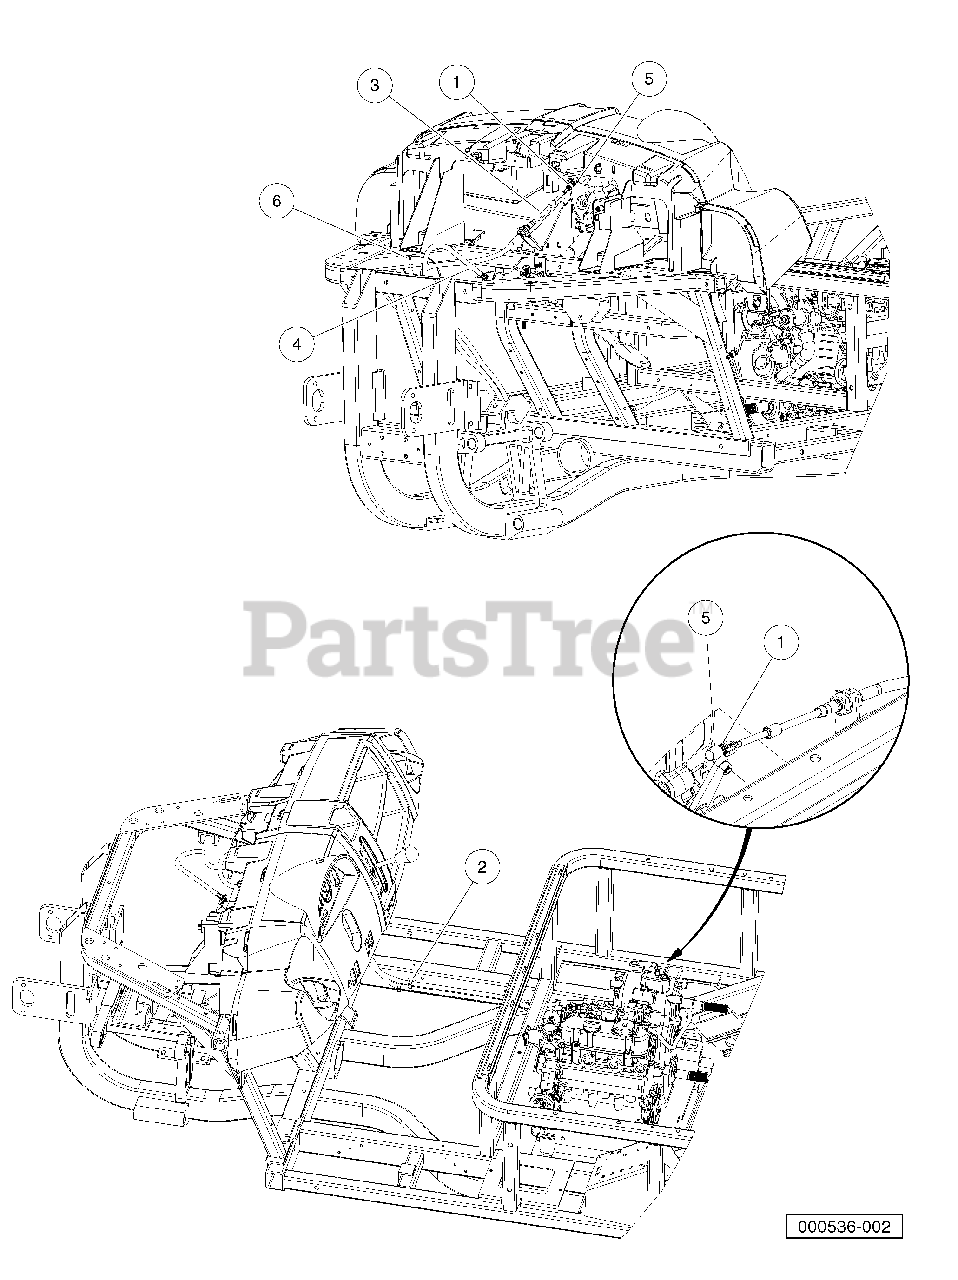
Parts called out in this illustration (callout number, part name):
1	Nut, 1/4-28 Hex Jam
2	Clip, Brake Line
3	Cable, Transmission Shift
4	Cable, Accelerator, Diesel
5	Joint, Ball, .346 Dia
6	Tie Wrap, 8" Nylon
